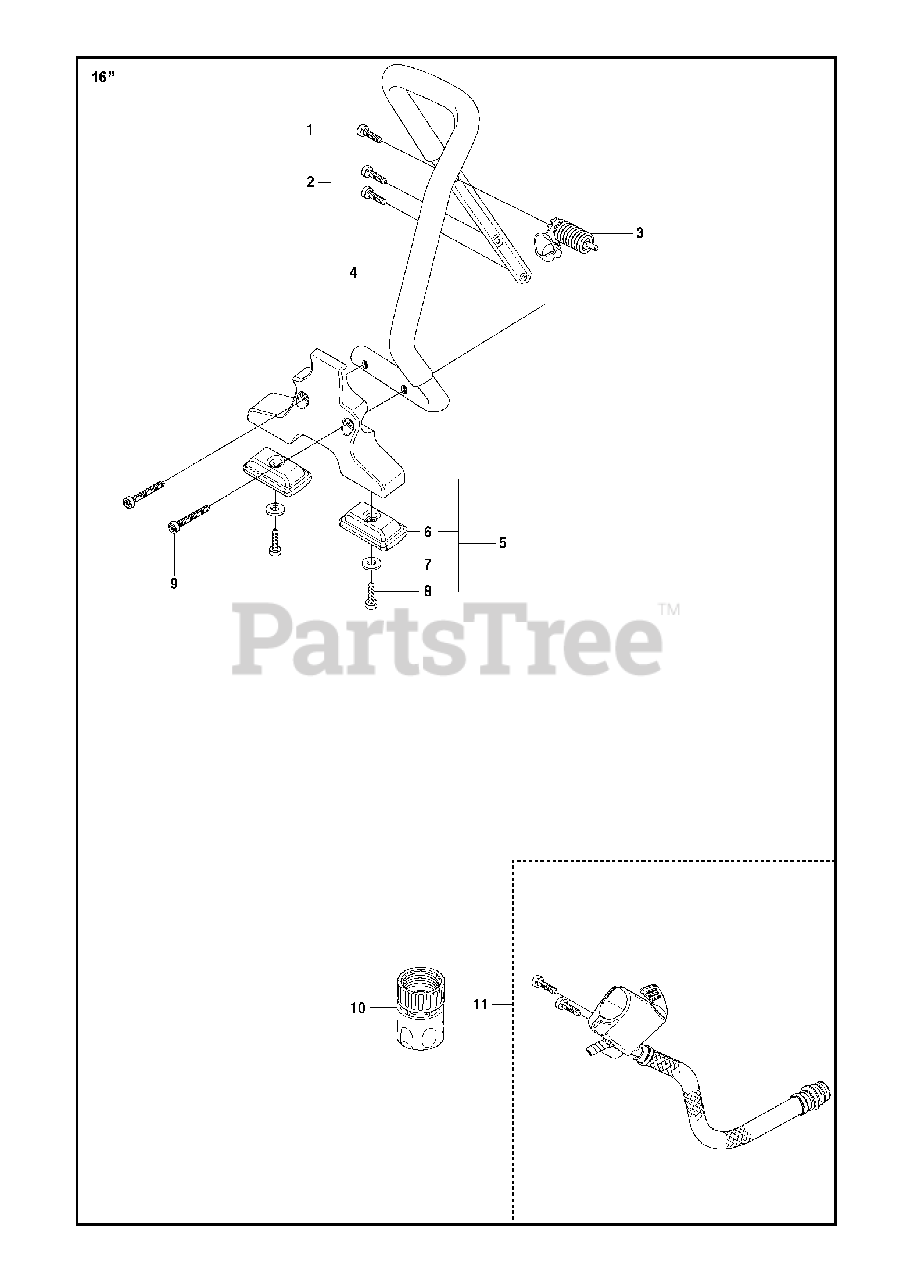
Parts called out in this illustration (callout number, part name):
1	SCREW ITXSCM
2	SCREW ITXSCT
3	ANTIVIBRATION ELEMENT
5	GROUND SUPPORT
8	SCREW ITXSCM
9	SCREW ITXSCT
